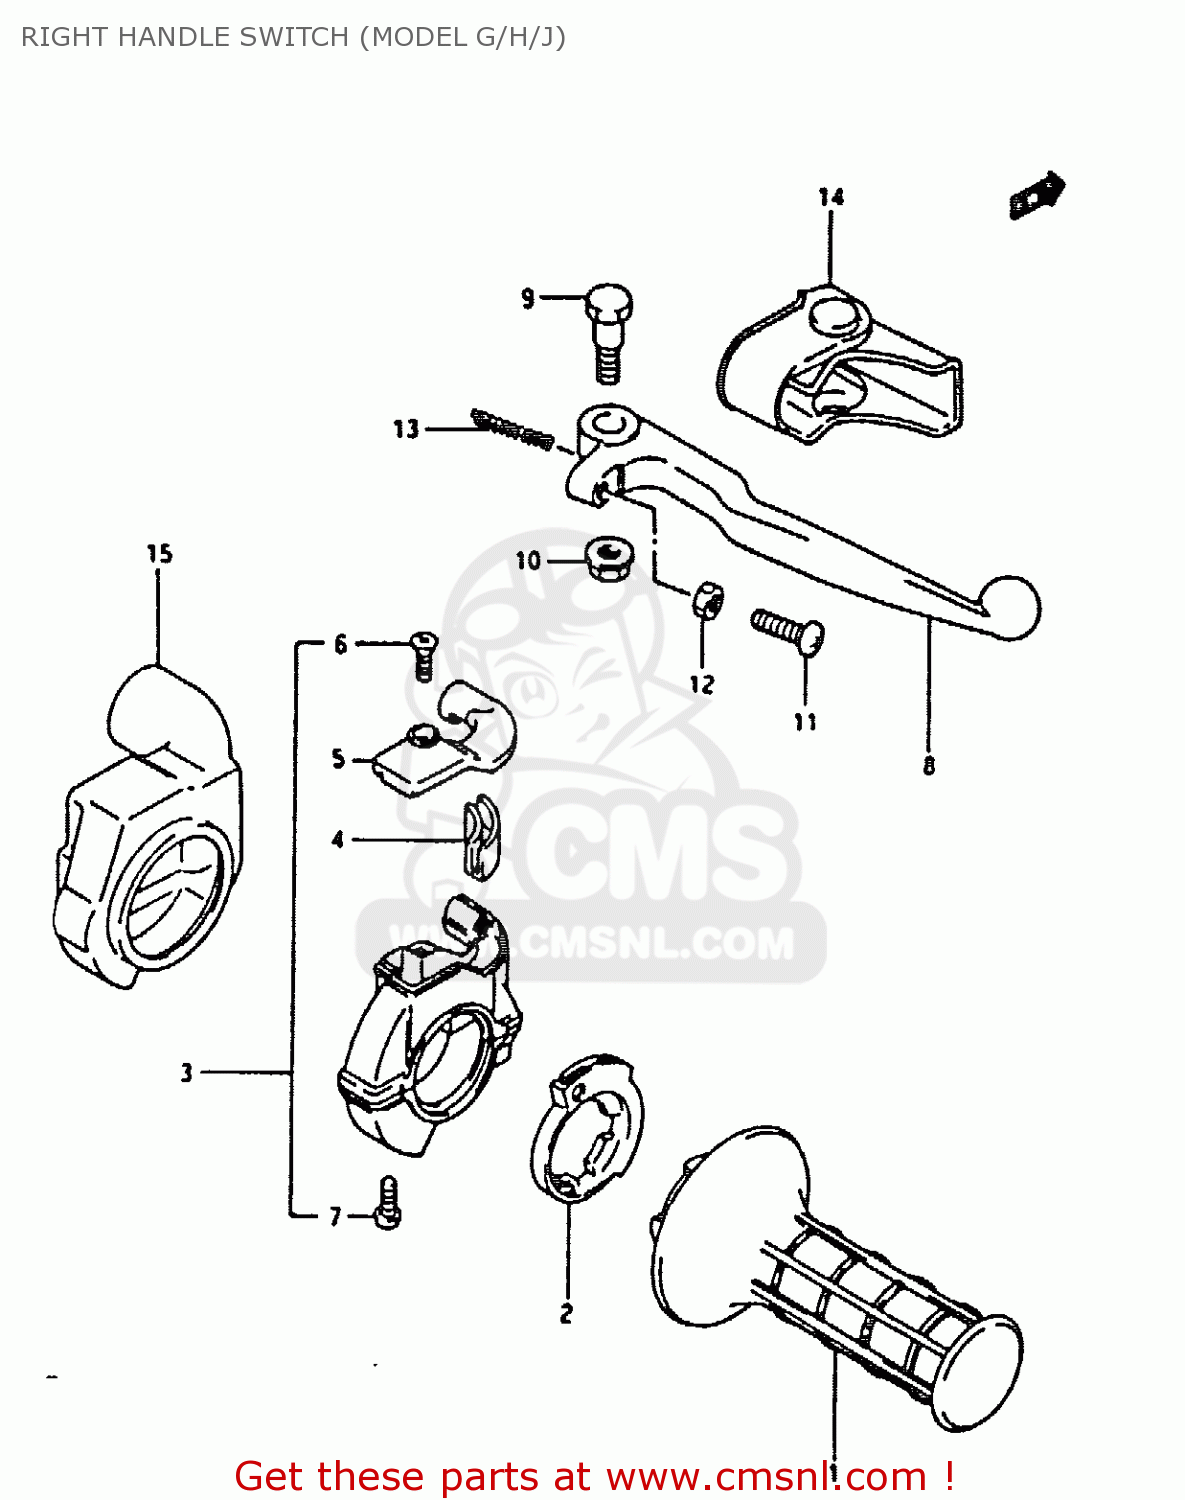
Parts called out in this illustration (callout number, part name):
1	GRIP,THROTTLE
2	ROTOR,THROTTLE GRIP
3	CASE ASSY,THROTTLE
4	GUIDE PIECE,THROTTLE
5	COVER,THROTTLE CASE
6	SCREW 4X10
7	SCREW
8	LEVER,BRAKE
9	BOLT,BRAKE LEVER
10	NUT,BRAKE LEVER
11	BOLT,ADJUST
12	NUT 5MM
13	SPRING,RETURN
14	COVER,BRAKE LEVER
15	COVER,THROTTLE CASE
